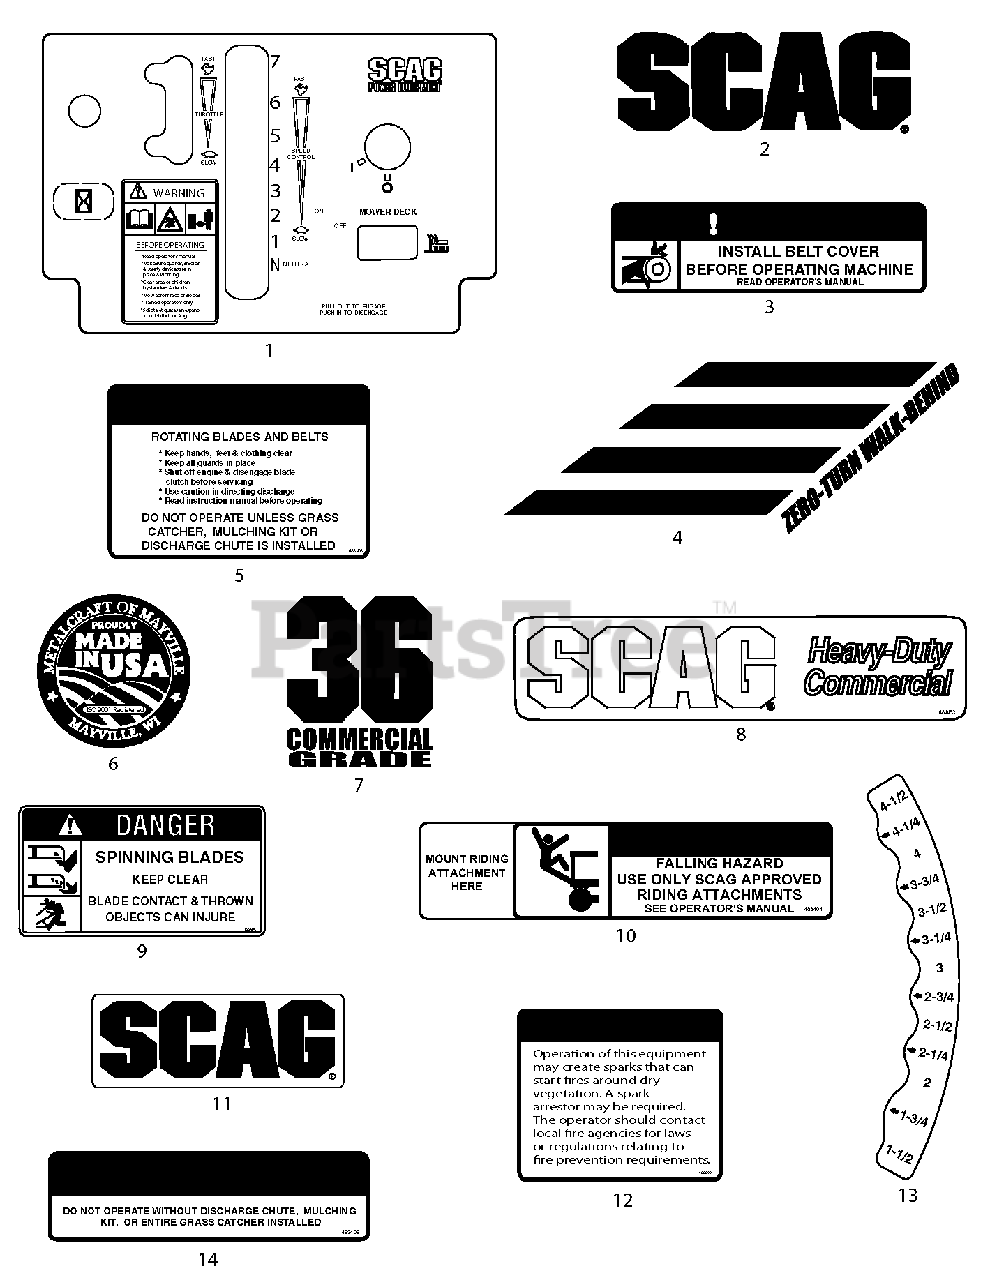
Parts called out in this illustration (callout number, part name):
1	Decal, Instrument Panel (Manual Start)
1	Decal, Instrument Panel (Electric Start Only)
2	Decal, Scag Logo
3	Decal, Belt Cover
4	Decal, Handle - LH
4	Decal, Handle - RH
5	Decal, Warning-Rotating Blades
6	Decal, Metalcraft - Made in USA
7	Decal, 36 Commercial
7	Decal, 48 Commercial
7	Decal, 52 Commercial
8	Decal, Scag Heavy Duty
9	Decal, Spinning Blades
10	Decal, Sulky Attachment
11	Decal, Scag Logo
12	Decal, Warning Spark Arrestor
13	Decal, Height of Cut
14	Decal, Warning
